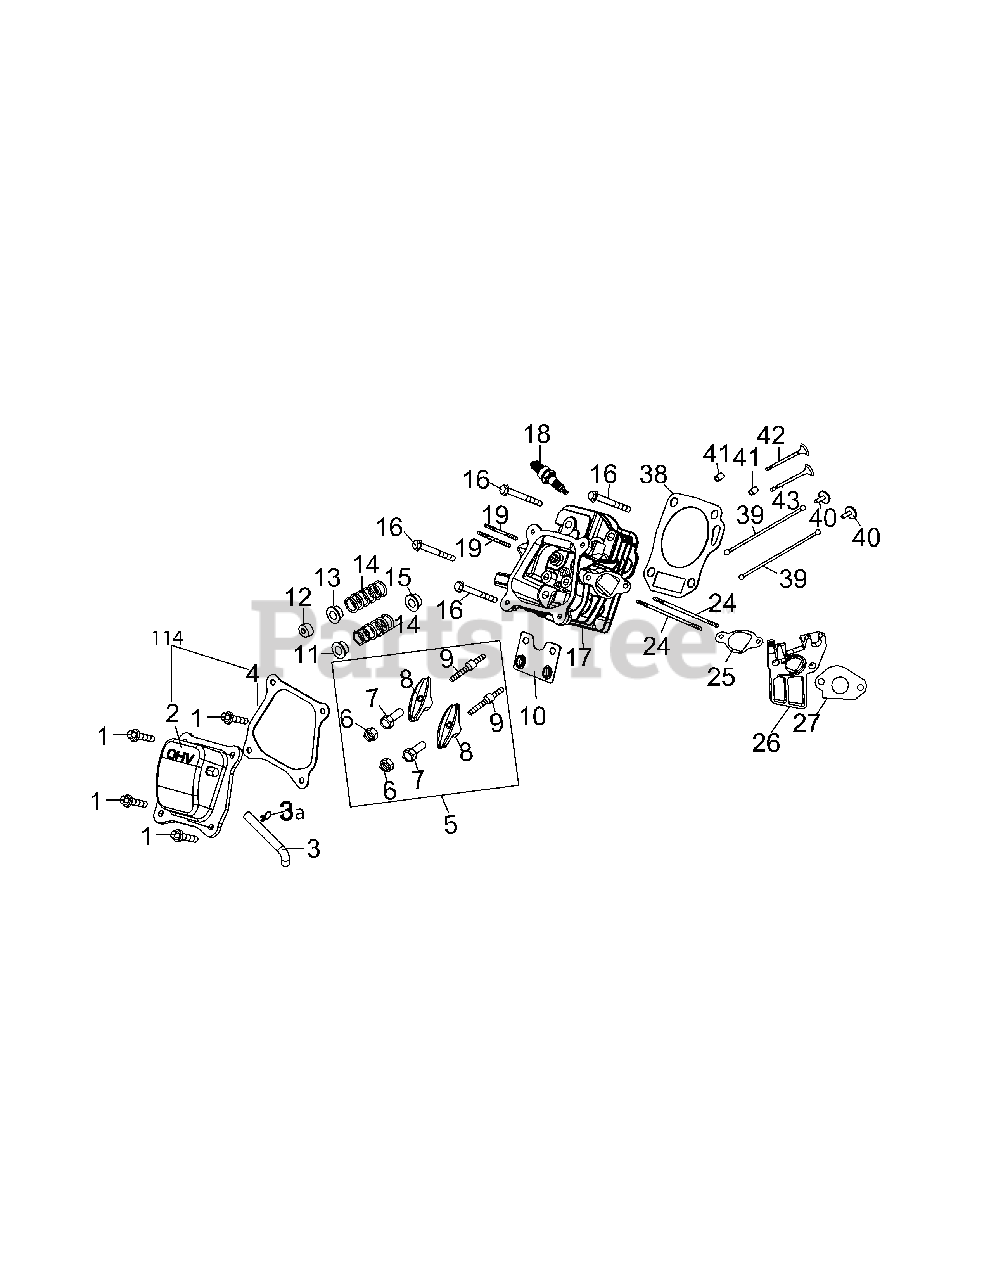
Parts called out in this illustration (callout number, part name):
1	Bolt M6×16
2	Valve Cover
3	Breather Hose
4	Valve Cover Gasket
5	Rocker Arm Assembly
6	Nut, Pivot Locking
7	Adjusting Nut, Valve
8	Rocker Arm
9	Bolt, Pivot
10	Push Rod Guide
11	Retainer, Intake Valve Spring
12	Adjuster, Exhaust Valve
13	Retainer, Exhaust Valve Spring
14	Valve Spring
15	Intake Valve Seal
16	Bolt M8×55
17	Cylinder Head Assembly
18	Spark Plug
19	Muffler Stud M8×36
19	Muffler Stud Assembly
24	Stud M6×110
25	Carburetor Insulator Gasket
26	Carburetor Insulator
27	Carburetor Gasket
38	Gasket, Cylinder Head
41	Dowel Pin 10×16
114	Valve Cover Kit
